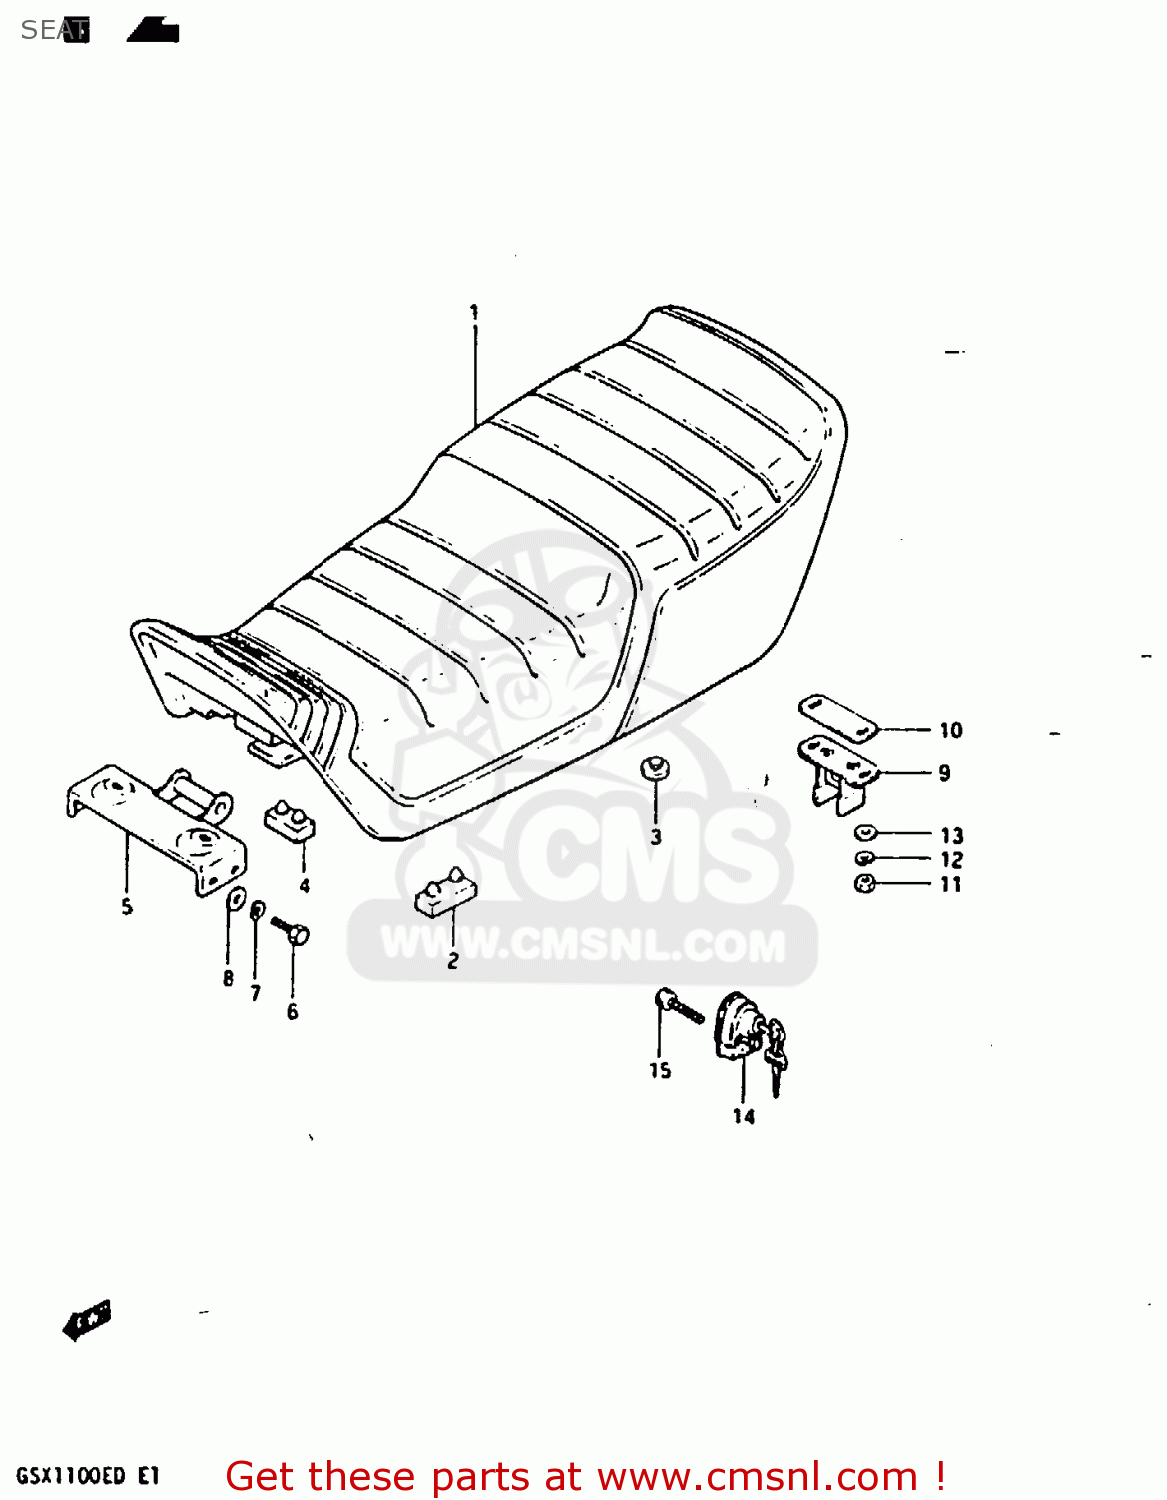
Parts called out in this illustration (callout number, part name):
1	SEAT ASSY (BLACK)
2	CUSHION
3	CUSHION
4	CUSHION
5	PLATE,SEAT HOOK
6	BOLT
7	LOCK WASHER
8	WASHER
9	STRIKER,SEAT LOCK
10	SHIM,SEAT LOCK STRIKER
11	NUT 6MM
12	LOCK WASHER
13	WASHER
14	LOCK ASSY,HELMET
15	BOLT 5X25
